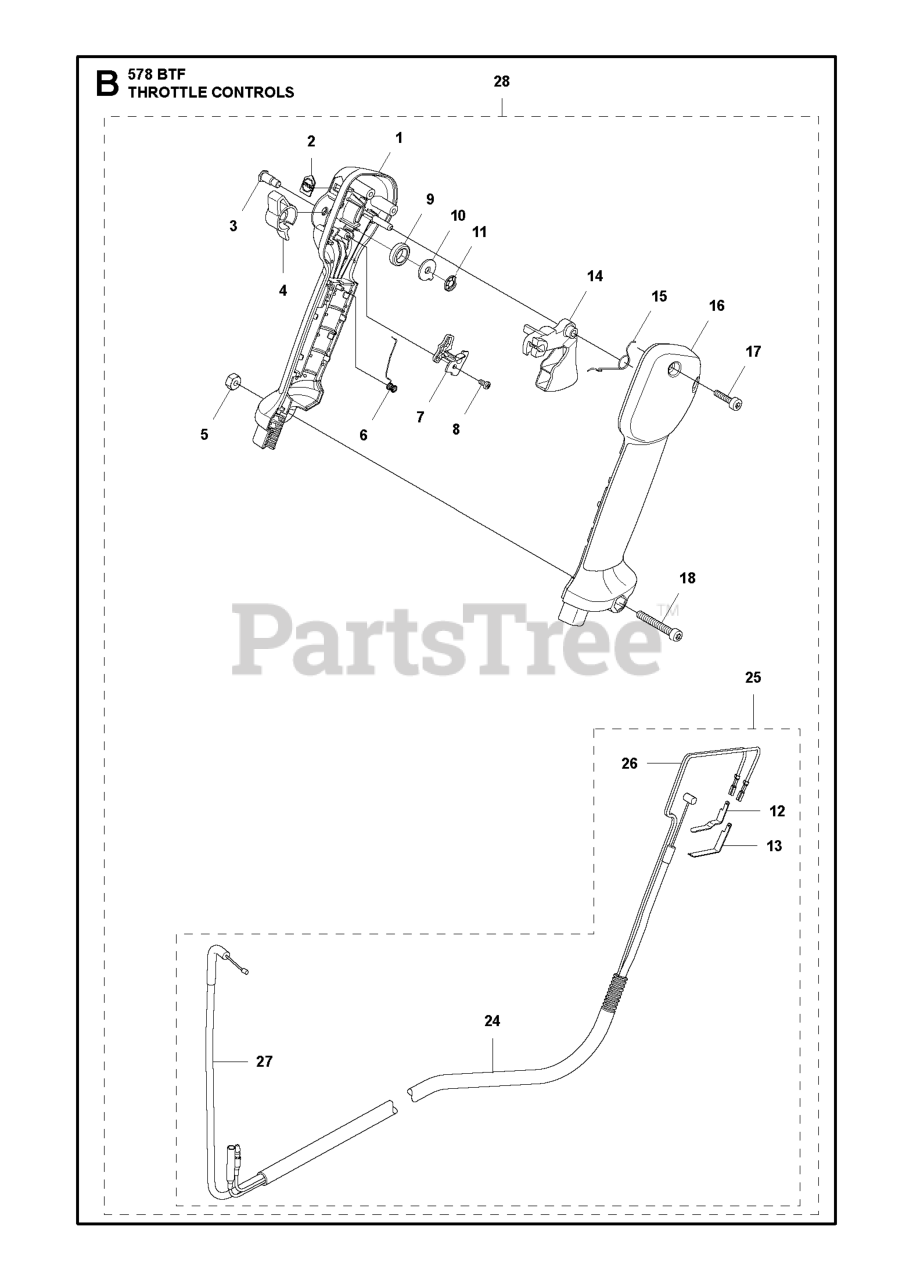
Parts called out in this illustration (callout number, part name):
1	HANDLE HALF (L)
3	SHAFT PIVOT
4	LEVER STOP
12	CONTACT SPRING
13	CONTACT SPRING
14	TRIGGER 848L5W34C0
16	HANDLE HALF (R)
17	SCREW
25	WIRING ASSY
26	CORD COMPLETE
27	CABLE, COMP
